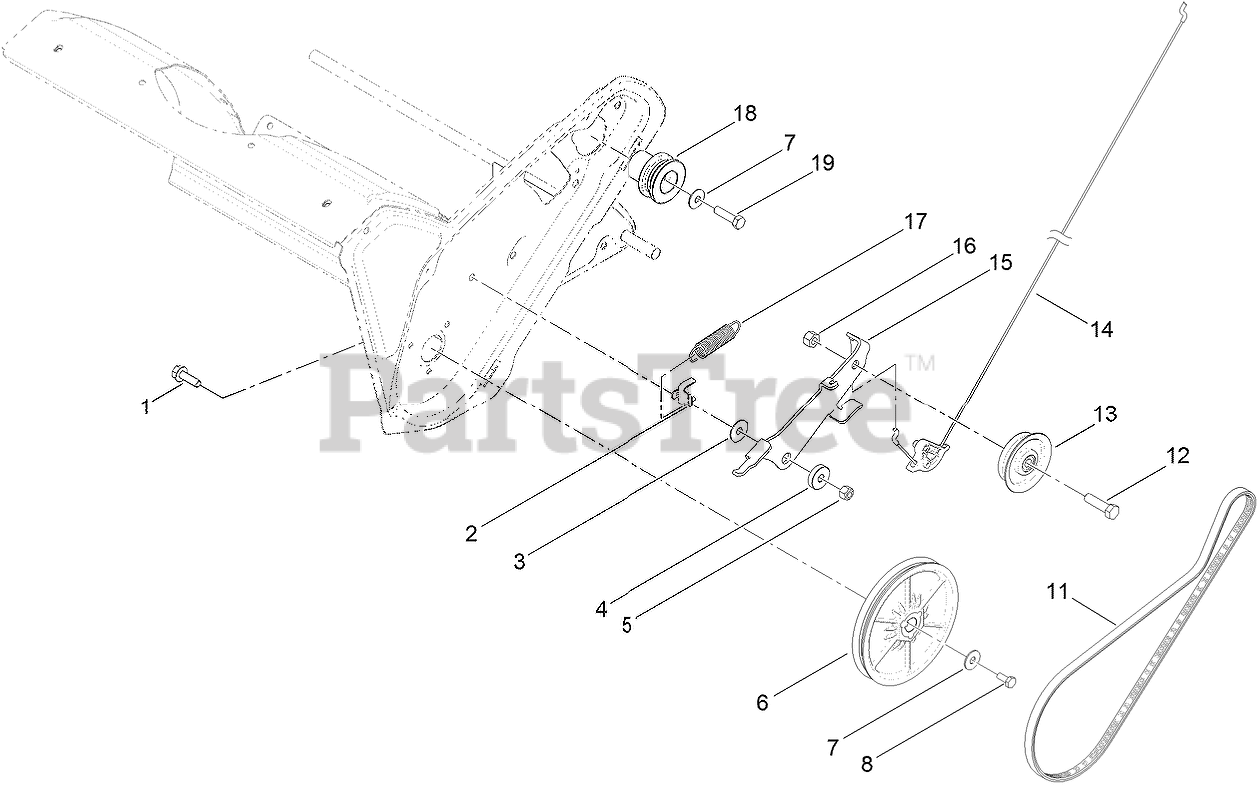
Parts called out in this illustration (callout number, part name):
1	SCREW-HHF
2	CLIP-SPRING, BRAKE
3	WASHER
4	BUSHING-PIVOT
5	NUT-LOCK, NI
6	ROTOR PULLEY ASM
7	WASHER-BELLEVILLE
8	SCREW-HH
11	BELT-DRIVE
12	SCREW-HH
13	PULLEY-IDLER
14	CABLE-CLUTCH
15	ARM-IDLER
16	NUT-LOCK, CONE
17	SPRING-EXTENSION
18	PULLEY-ENGINE
19	SCREW-HH
